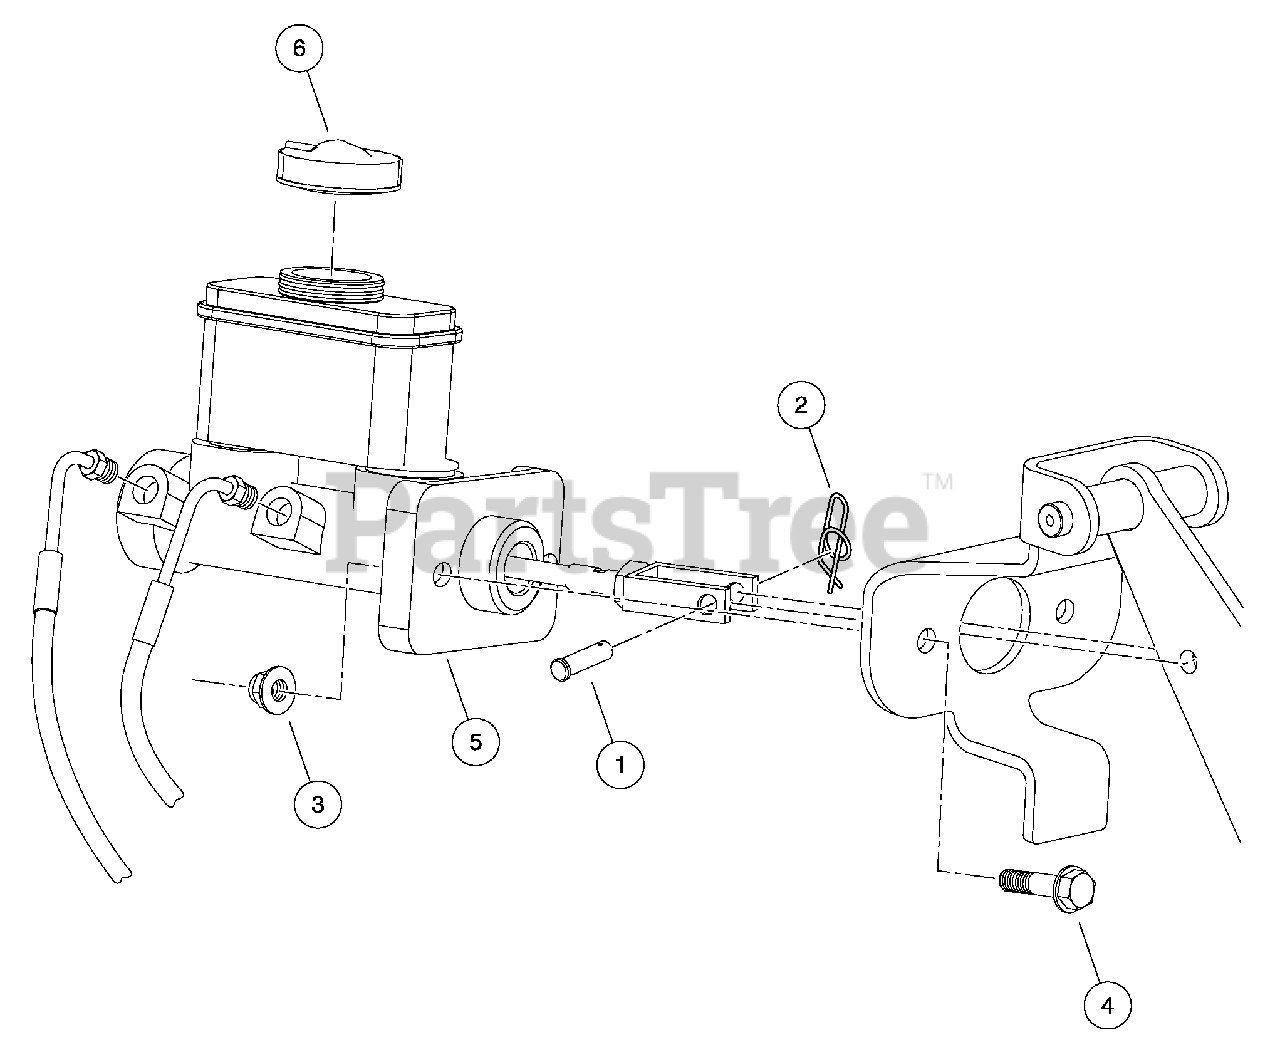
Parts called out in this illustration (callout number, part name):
1	Clevis Pin, 5/16 X 1
3	Nut,m8,all Metal Lock
4	Bolt Flanged Head, M8 X 1.25 X 35
5	Cylinder, Master, Integral Res
6	Filler Cap Asm Integral Res
